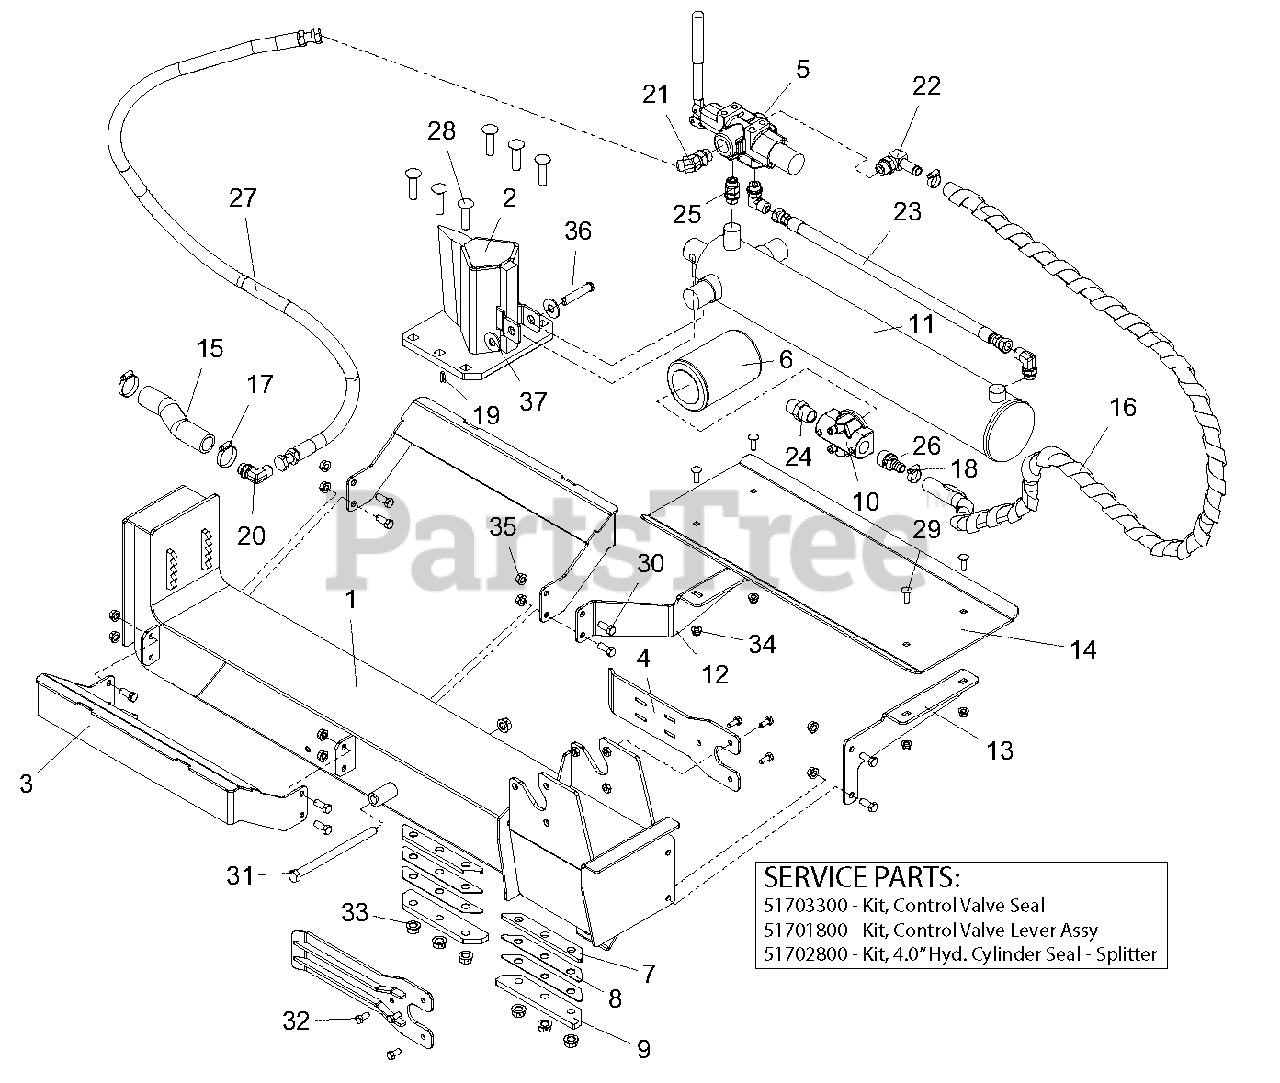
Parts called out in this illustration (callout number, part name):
1	WLDMT, BEAM - 22 TON SPLITTER
2	WLDMT, WEDGE - SPLITTER
3	WLDMT, CRADLE - LOG SPLITTER
4	PLATE, STRIPPER - RED
5	VALVE, CONTROL - SPLITTER
5	KIT, CONTROL VALVE SEAL
5	KIT, CONTROL VALVE LEVER ASSY
6	FILTER, OIL - W/BYPASS
7	SPCR, WEDGE
8	SHIM, SPLITTER WEDGE
9	RETAINER, WEDGE-BLACK
10	HEAD, FILTER -3/4 NPT BYPASS
11	CYLINDER, SPLITTER - 4.0"
11	KIT, 4" HYDRAULIC CYLINDER SEAL - SPLITTER
12	BRKT, REAR - WORK TABLE
13	BRKT, FRONT - WORK TABLE
14	TABLE, WORK - LOG SPLITTER
15	HOSE, HYD SUCTION, 6.75"
16	HOSE, HYD -RETURN 74"LG
17	CLAMP, HOSE 1.50 X .81 X 1.42
18	CLAMP, .88 DIA HOSE
19	CLIP, SPRING
20	FTG, HYD. 2501-8-8
21	FTG, HYD. 6802-8-10
22	FTG, HYD. 4601-10-10
23	HOSE, ASSY, 8M3K-8FJX-8FJX-22
24	FITTING, HYD 5404-12-12
25	FTG, HYD - STR 08MAORB-08MORB
26	FTG, HYD 3/4"NPT X 5/8" ID HOSE BARBED
27	HOSE, HYD 8M3K-8FJX-58
28	@BLT-RDHDSQNK .50-13X2.00 G8 Y
29	BLT-RDHDSQSHNK .31-18X1.00 G5YWZC
30	BLT-HEX .38-16X1.00 GR5 YWZC
31	BLT-HEX .50-13X7.50 GR5 YWZC
32	BLT-HEX .31-18X.75 GR5 YWZC
33	NUT-LK-CTR-FLG .50-13 YWZC
34	NUT-LK-NYL-FLG .31-18 YWZC
35	NUT, LK-TOP-FLG .38-16 YWZC
36	PIN-CLEV .494X2.50X2.27 YWZC
37	WSHR-FL-STL .563X1.38X.109YWZC
